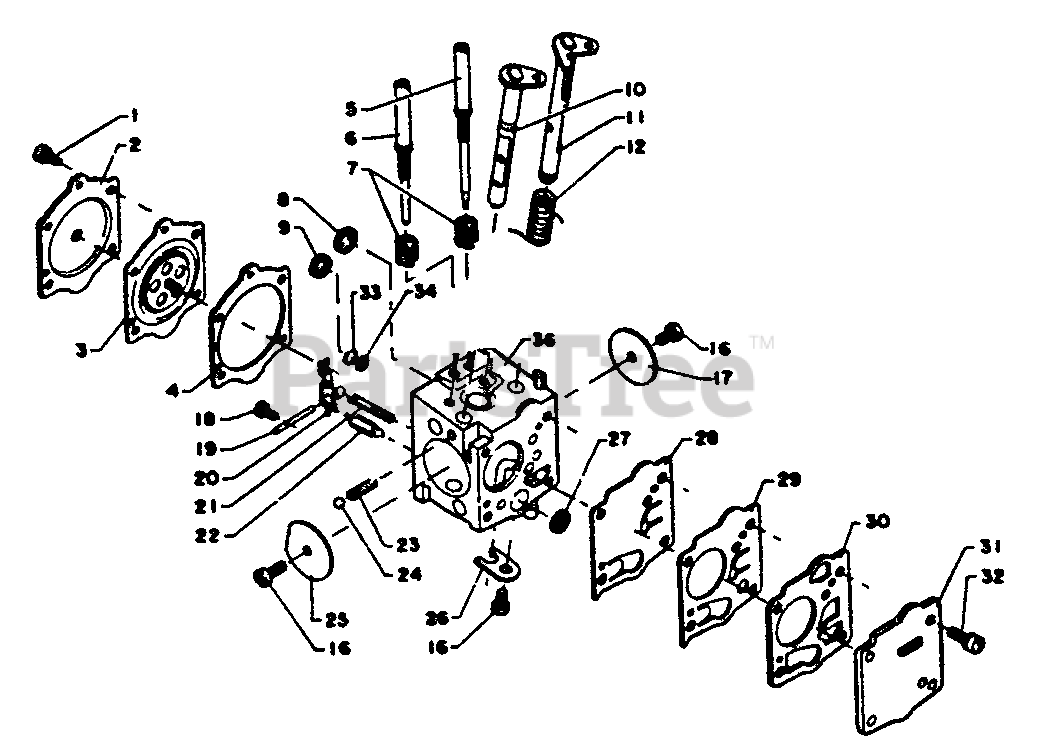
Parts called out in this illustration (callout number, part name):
2	COVER, DIAPHRAGM
3	DIAPHRAGM, METERING
4	GASKET, METERING DIAPHRAGM
5	NEEDLE, IDLE
6	NEEDLE, HIGH SPEED
7	SPRING, NEEDLE
8	PLUG, WELCH
9	PLUG, WELCH
10	SHAFT, CHOKE
11	SHAFT, THROTTLE
17	VALVE, THROTTLE
18	SCREW, METERING LEVER PIN
19	PIN, METERING LEVER
20	LEVER, METERING
22	VALVE, INLET NEEDLE
23	SPRING, CHOKE
24	BALL, CHOKE
25	VALVE, CHOKE
26	RING, RETAINING
27	STRAINER
28	DIAPHRAGM, FUEL PUMP
29	DIAPHRAGM, CHECK VALVE
30	GASKET, FUEL PUMP
31	COVER, PUMP
32	SCREW
33	RING, RETAINING
34	SCREEN, CHECK VALVE
36	BODY, CARBURETOR
